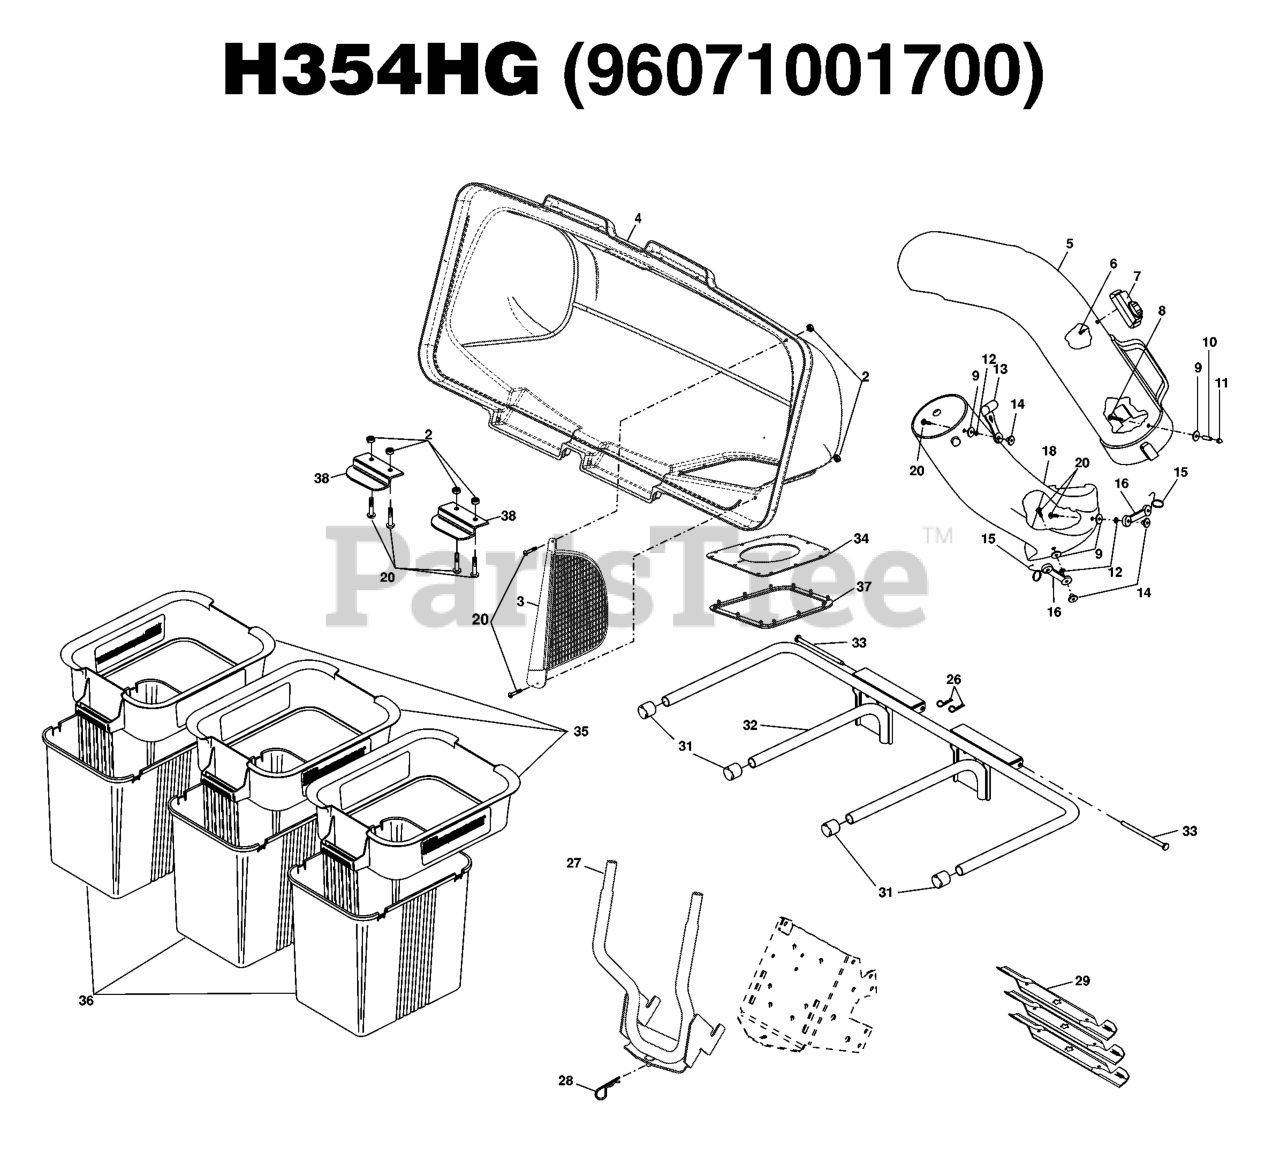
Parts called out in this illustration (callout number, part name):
3	SCREEN.COVER.BAGGER
4	COVER.ASM.3BIN.GENERIC.
5	UPPER CHUTE 54"
7	INDICATOR ASM BAG
8	SCREW
11	NUT
12	LOCKWASHER #10
13	LATCH.HOOD.
14	WELDNUT
15	HOOK LATCH
16	RUBBER LATCH
18	CHUTE.BAGGER.LOWER.54"
20	SCREW
26	RETAINER-SPRNG RB
28	SPRING.RETAINER.YELLOW.ZINC
29	BLADE.BAGGING.54"
31	PLUG, TUBING END
32	BAGGER.ASM.FRAME.3BIN.BLACK
33	BAGGER.HINGE.PIN
34	SEAL.BAGGER.TOP.3-BIN.BLK
35	CONTAINER TOP
36	CONTAINER BOTTOM
37	GASKET.COVER.BAGGER
38	LATCH CER38
